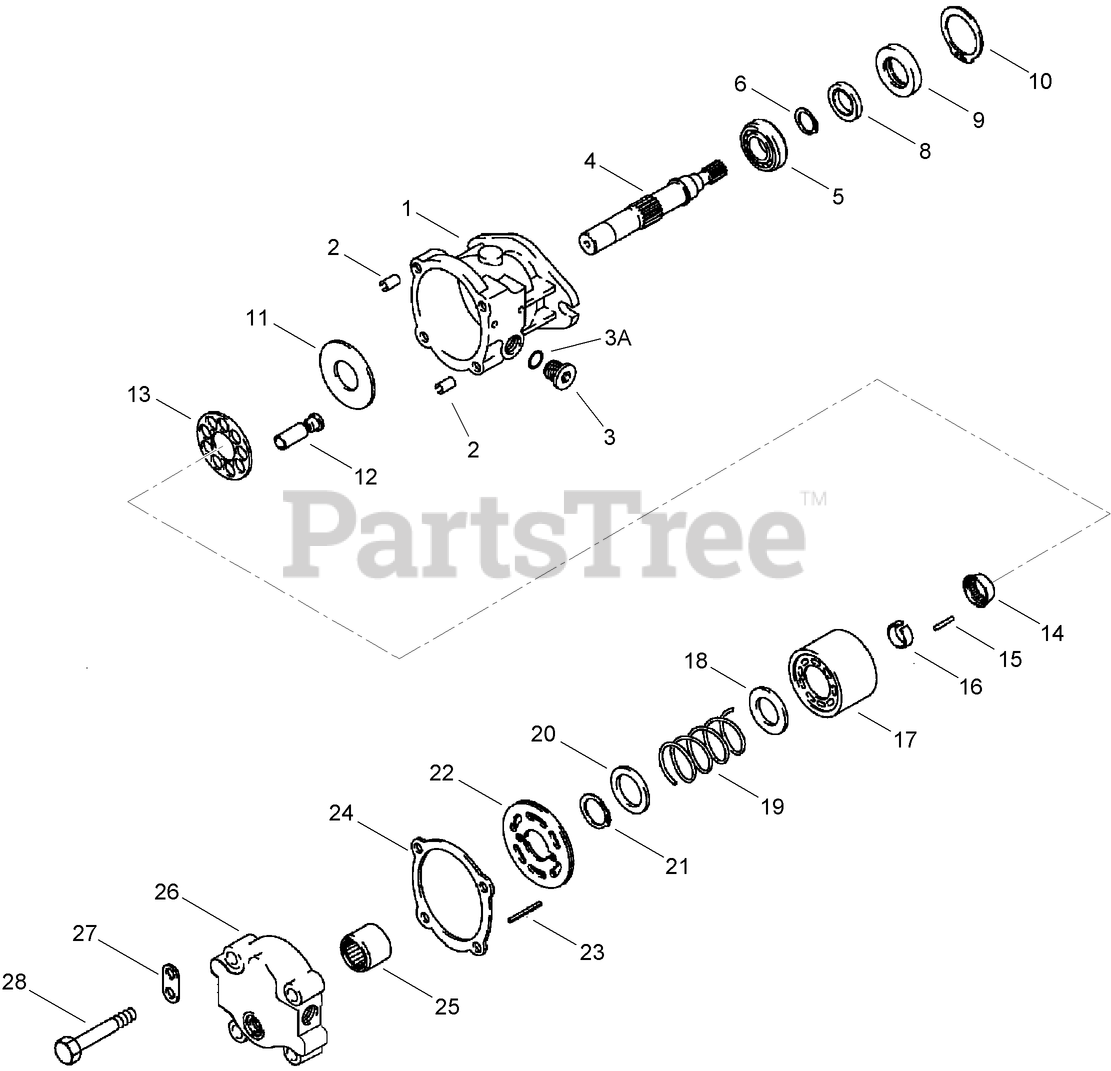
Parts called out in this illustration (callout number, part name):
1	HOUSING - Motor
2	PIN-Spring
3	PLUG-SOCKET HEAD
3A	O-RING
4	SHAFT - Motor
5	BEARING
6	RING-RETAINING
8	SEAL-BEARING, CARRIER
9	WASHER-SUPPORT, SEAL
10	RING-RETAINING, INT
11	PLATE-Thrust
12	PISTON - Cylinder Block
13	RETAINER - Piston
14	GUIDE - Retainer
15	PIN - Retaining, Guide to Shaft
16	Ring - Retaining
17	BLOCK - Cylinder
18	SEAT - Spring, Block End
19	SPRING - Cylinder Block
20	SEAT - Spring, Cover End
21	Ring - Retaining
22	PLATE-Valve
24	GASKET-End Cap
25	BEARING - Needle, Shaft
26	COVER - End, with Ports
27	BRACKET-Lifting
28	BOLT - Hex, 10 - 1.5 x 80 mm, Class 10.9
